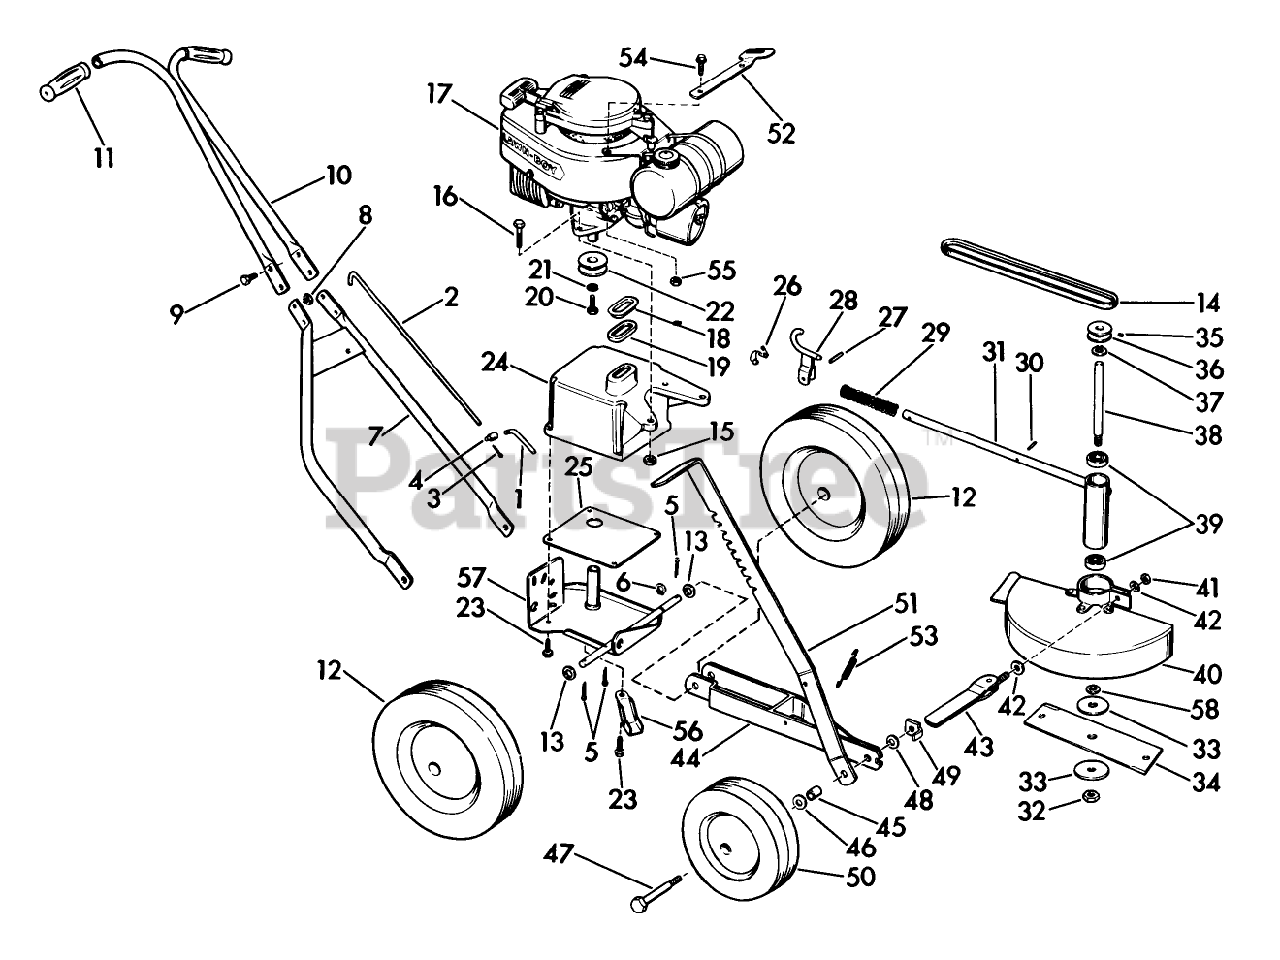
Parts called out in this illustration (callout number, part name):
8	STOP NUT
17	Engine-C-74
21	WASHER, LOCK
34	Blade-9"
44	Wheel Bracket and Spacer Assy.
48	WASHER, LOCK
